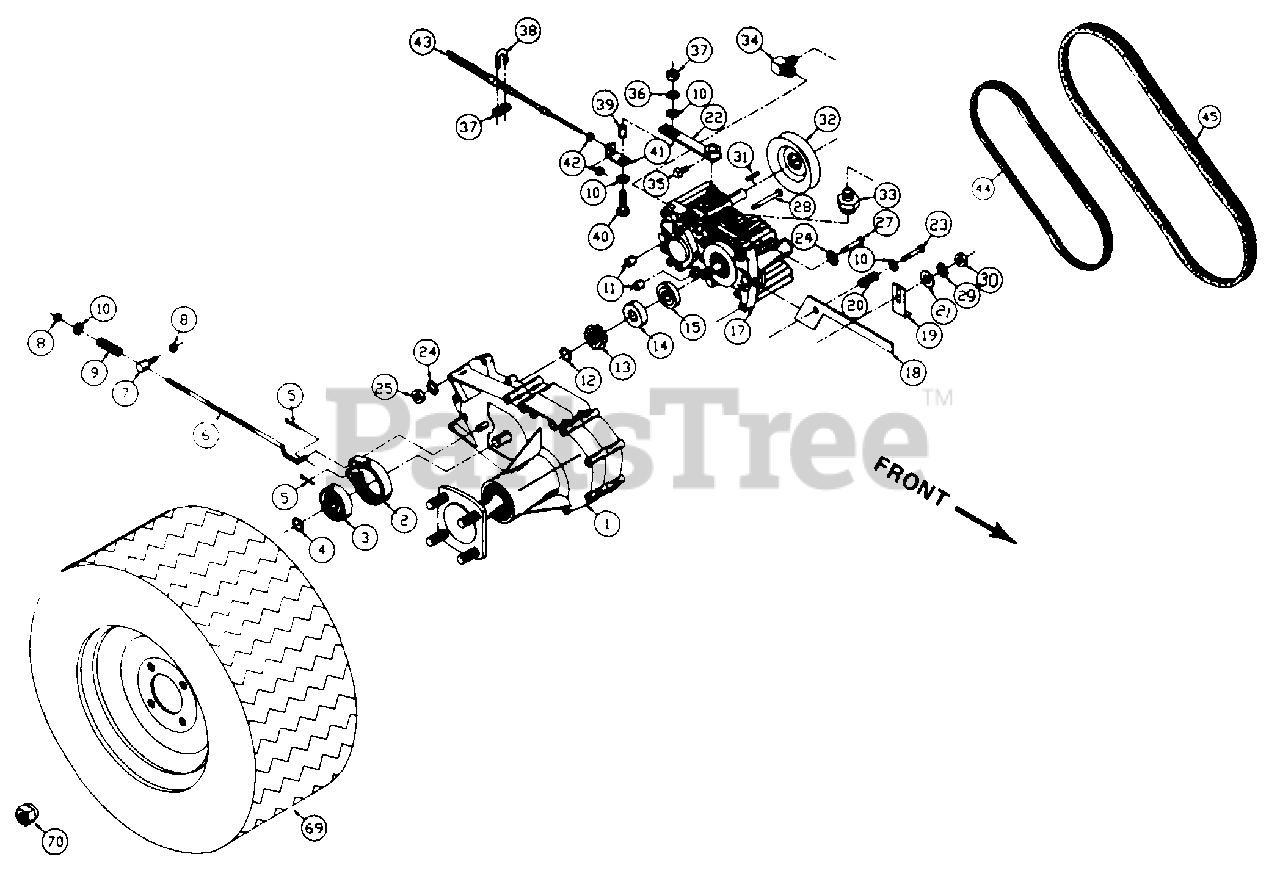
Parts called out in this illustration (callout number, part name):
1	ZT Transmission
5	Cotter Pin, 1/8" x 1"
6	Brake Linkage Rod
7	Caliper Rod Collar
8	Elastic Stop Nut, 1/4-20
10	Flatwasher, 1/4"
12	Snap Ring
14	Bearing
17	Sundstrand Pump, RH
18	Transmission Dump Lever
19	Transmission Dump Lever Stop
20	Compression Spring, 9/16" OD x 1 3/8"
21	Flatwasher, 3/8"
22	Transmission Arm
23	Dump Valve Bolt
24	Lockwasher, 5/16"
25	Hex Nut, 5/16-18
27	Hex Bolt, 5/16-18 x 2", GR5
28	Hex Bolt, 5/16-18 x 7 1/2", GR5
29	Lockwasher, 3/8"
30	Hex Nut, 3/8-16
31	Key, 5 x 5 x 25mm
32	Pulley, 4" OD x 15mm ID
33	Male Tube, Male O-ring Adapter
34	Male Tube, 90° Male O-ring Adpt.
35	Squarehead Setscrew, 5/16-18 x 1/2"
36	Lockwasher, 1/4"
37	Hex Nut, 1/4-20
38	Steering Cable Clamp
39	Steering Cable Bushing
40	Hex Bolt, 1/4-20 x 1", GR5
41	Steering Cable End
42	Hex Nut w/Star Washer, 10-32
43	Steering Cable, 3/16" x 58"
44	Pump Drive Belt
45	Belt
69	Drive Wheel Assembly
70	Lug Nut, 1/2-20
